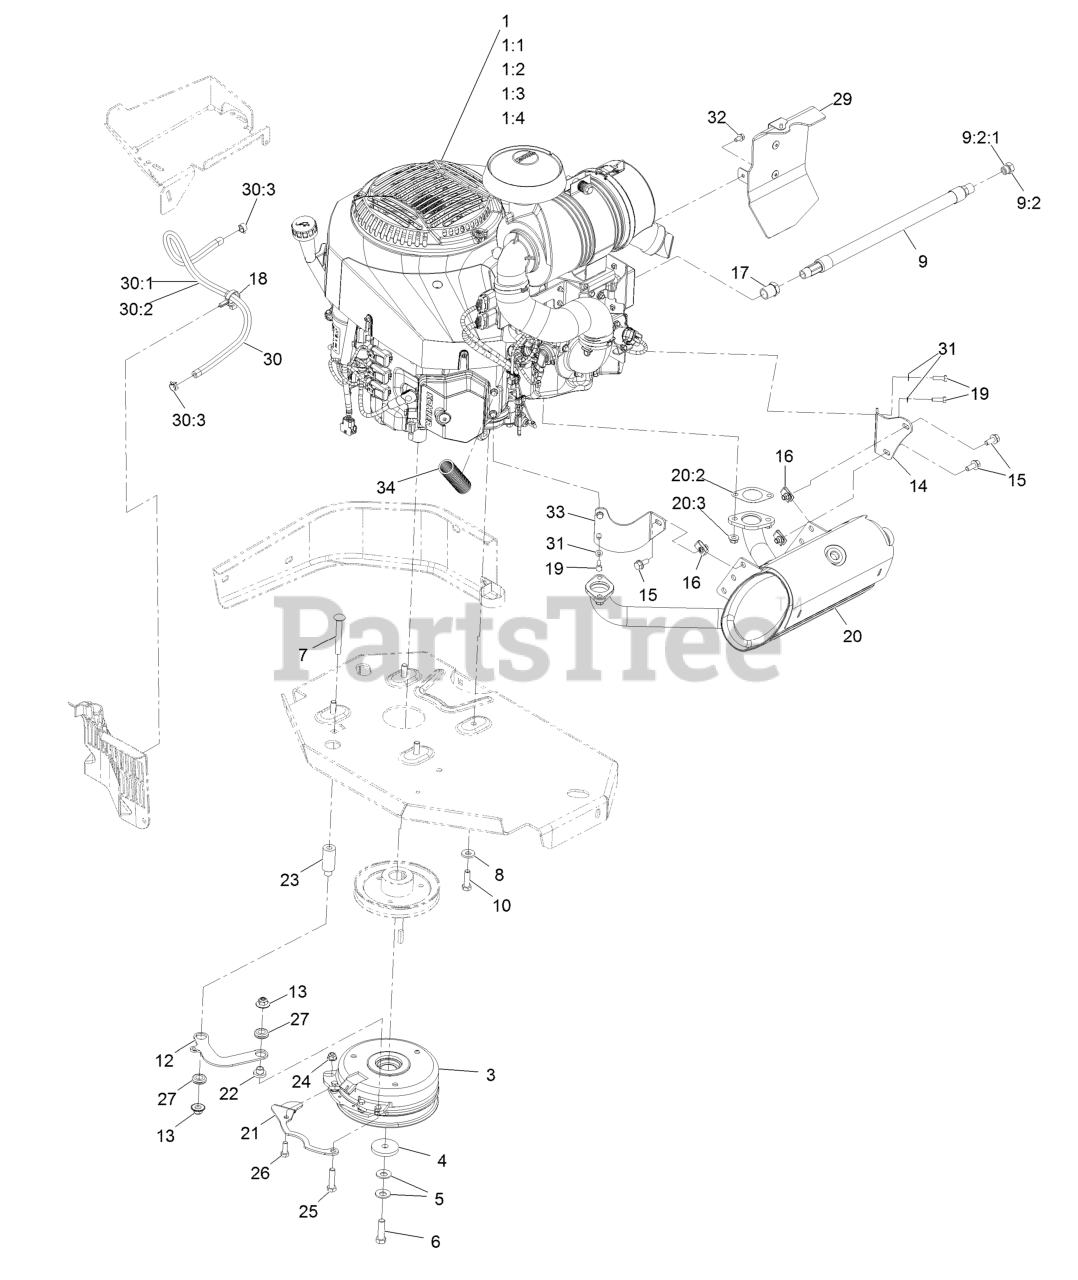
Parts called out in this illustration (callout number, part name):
1:1	Kohler 52 050 02-S Engine Oil Filter
1:2	Kohler 25 083 01-S Engine Air Filter
1:3	Kohler 25 083 04-S Safety Filter
1:4	Kohler 25 050 42-S Fuel Filter
3	Clutch Kit
4	Washer-Clutch
5	Washer-Spring Disc 7/16
6	Screw-HH 7/16-20 X 1 1/2 W/Loctite
7	Bolt-Carriage 3/8-16 X 3
8	Washer-Spring Disc 3/8
9	Oil Drain Hose ASM
9:2	Plug-W/O-Ring
9:2:1	O-Ring
10	Screw-HH 3/8-16 X 1 1/4
12	Link-Anchor, Clutch
13	Nut-Nyloc 3/8-16 Flg
14	Bracket-Muffler
15	Screw-HH Flg 5/16-18 X 3/4
17	Bushing
18	Clamp-Hose
19	Screw-HH M6-1 X 20Mm W/Patch
20	Muffler Kit
20:2	Gasket-Exhaust
20:3	Nut-Flange, Lock
21	Belt-Guide
24	Nut-Nyloc 5/16-18 Flg
25	Screw-HH 3/8-16 X 1 1/2
26	Screw-HH 5/16-18 X 7/8
27	Grommet-Rubber
29	Rear Baffle ASM
30	Fuel Line ASM
30:1	Hose-Fuel Line 29"
30:2	Sleeve, Thermal
30:3	Clamp-Hose
31	Washer-Spring Disc 1/4
32	Screw-HWH M6-1 X 12Mm Tf
33	Bracket-Muffler, Front
34	Conduit-Convoluted
